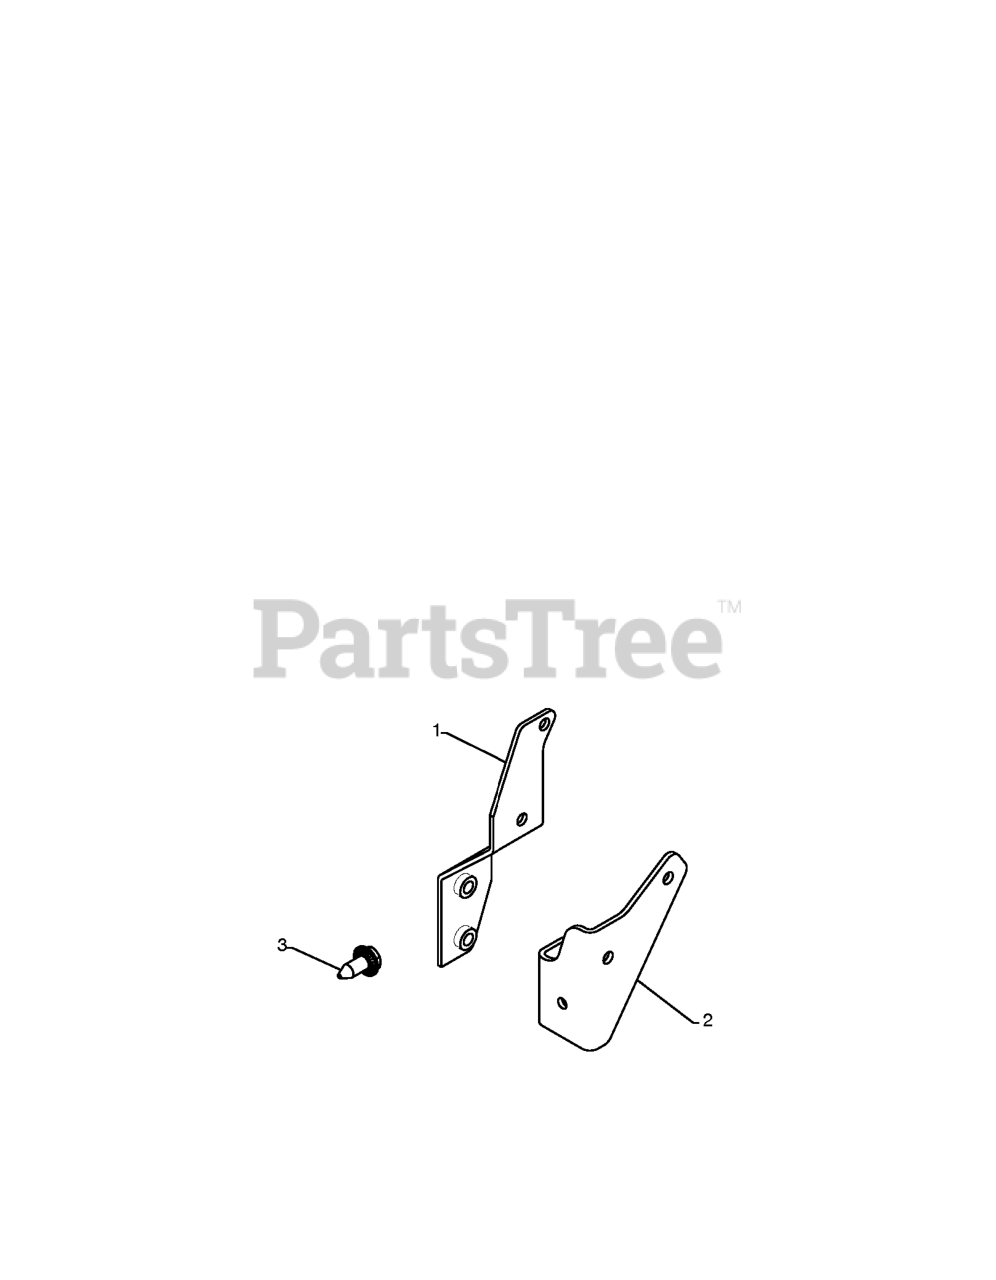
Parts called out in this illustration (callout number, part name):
1	STRAP.TORQUE.HYDRO
2	BRACKET, ANTI-ROTATE
3	SELF-TAPPING SCREW 5/16-18X3/4
